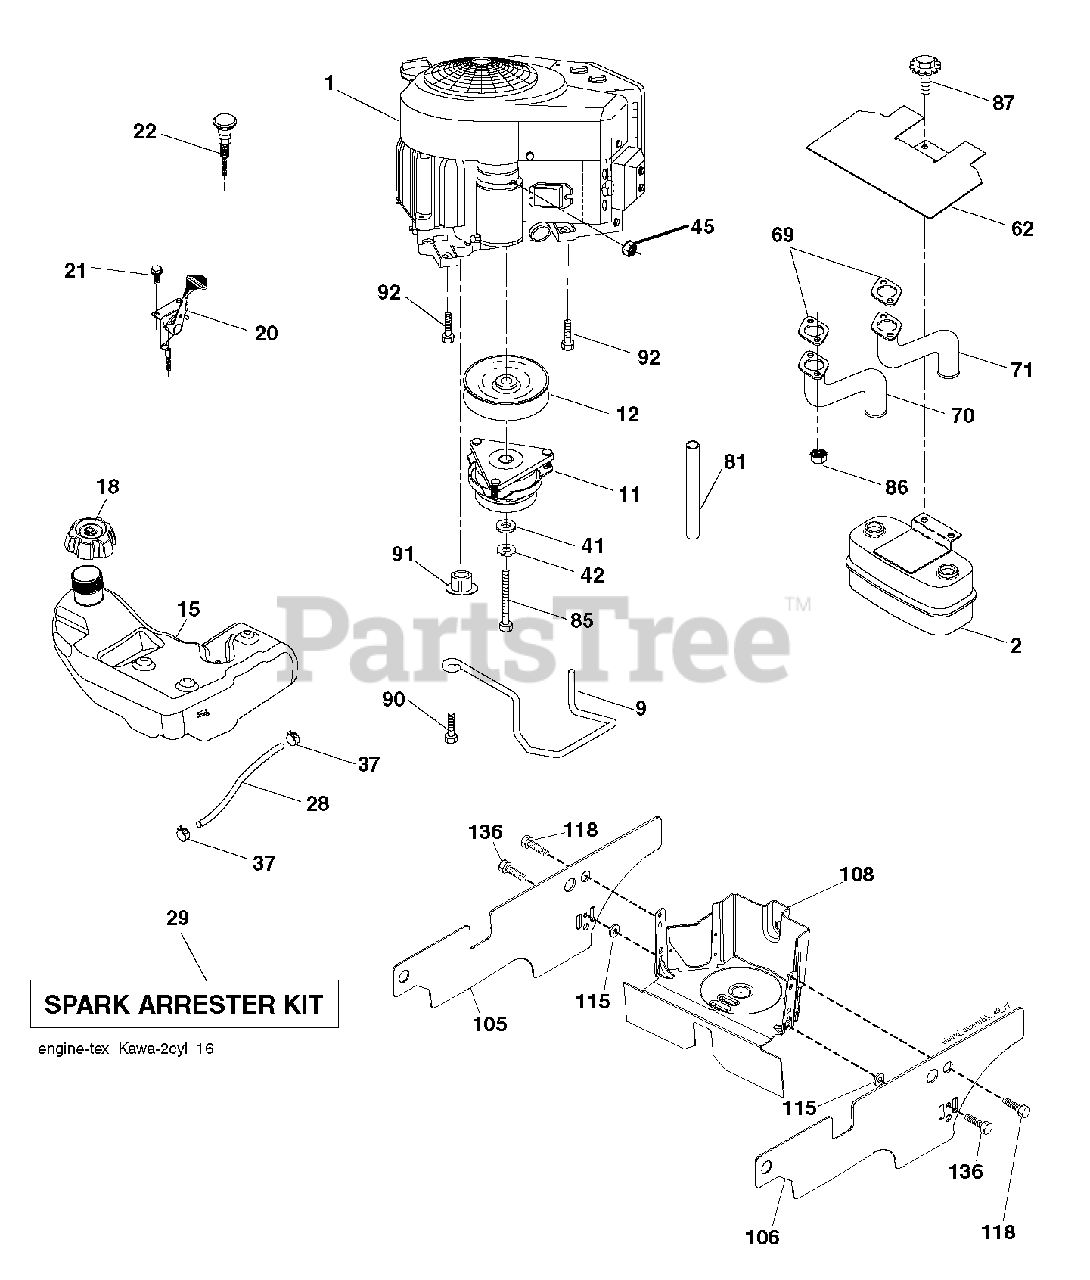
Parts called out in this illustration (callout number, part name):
2	MUFFLER.ASM.TWN.EXTNDED.DFLCTR
9	KEEPER.BELT.ENGINE.4.2
11	CLUTCH.ELECTRIC.LT.48"*
12	PULLEY.ENGINE.TUFFTORQ
15	TANK.FUEL.4GAL
18	CAP.FL.R.3'N/CARB.H.CROWN.498
20	CONTROL.THROTTLE.COBRA.BLACK
21	SCREW.#10 X 0.750.BOS
22	CONTROL, CHOKE
28	REPL BY 532 00 85-43
29	KIT.SPARK ARRESTOR 794945 B&S
37	HOSE CLAMP
42	LOCKWASHER
45	NUT
62	SHIELD.HEAT.MUFFLER
70	TUBE.EXHAUST.LH.FR961/FR730
71	TUBE.EXHAUST.RH.FR961/FR730
81	TUBE, DRAIN OIL ASM.
85	BOLT HEX 7/16-20X4-1/4"
86	NUT.HEX.FLANGE.TOPLOCK
87	BOLT, 5/16-18 X 1 3/4
90	SCREW 3/8-16X1
91	BUSHING.1.375OD
92	SCREW 3/8-16X1
105	SHIELD.SIDE.RH.3842"TEX FRENCH
106	SHIELD.SIDE.RH.46"FRENCH.TEX
108	COVER
115	PALNUT 1/4
118	SCREW, 5/16-18 X 1/2
136	SCREW.1/4-20X5/8
